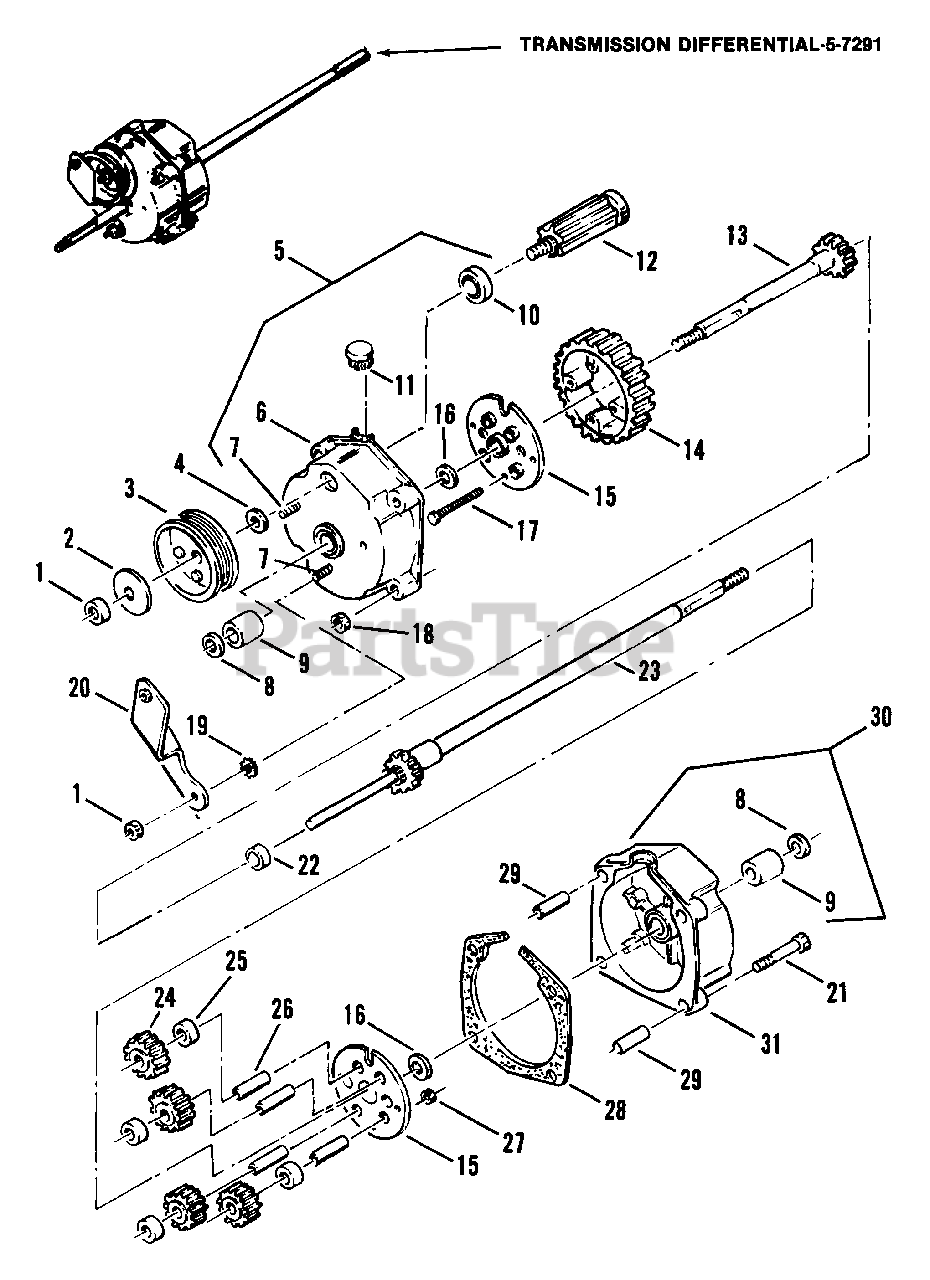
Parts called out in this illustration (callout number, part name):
1	NUT, 5/16-24 Hex Lock
2	WASHER, Spring
3	PULLEY, Poly-Vee Belt
4	WASHER, Spring
5	HOUSING ASSEMBLY, Right
5-7291	ASSEMBLY, Transmission
6	HOUSING, Right Side
7	SCREW, 5/16-24 x 1-1/8" Rib Neck
8	SEAL, 5/8" ID
9	BEARING, Differential
10	BEARING, Ball
11	PLUG, Housing
12	GEAR, Input
13	AXLE, Short
14	GEAR, Differential, 46 Tooth
15	PLATE
16	WASHER, Thrust
17	SCREW, 10-32 x 1-1/2" Hex Head Cap
18	NUT, 1/4-28 Hex Lock
19	WASHER, 5/16" Internal External Tooth Lock
20	BRACKET, Differential
21	SCREW, 1/4-28 x 1-3/8 Hex Head Cap
22	SPACER, Axle Gear
23	AXLE, Long
24	GEAR, Pinion, 12 Tooth
25	SPACER, Pinion Gear
26	SHAFT, Pinion
27	NUT, 10-32 Hex Lock
28	GASKET, Housing
29	PIN, 3/8-7/16" Roll
30	HOUSING ASSEMBLY, Left
31	HOUSING, Left Side
